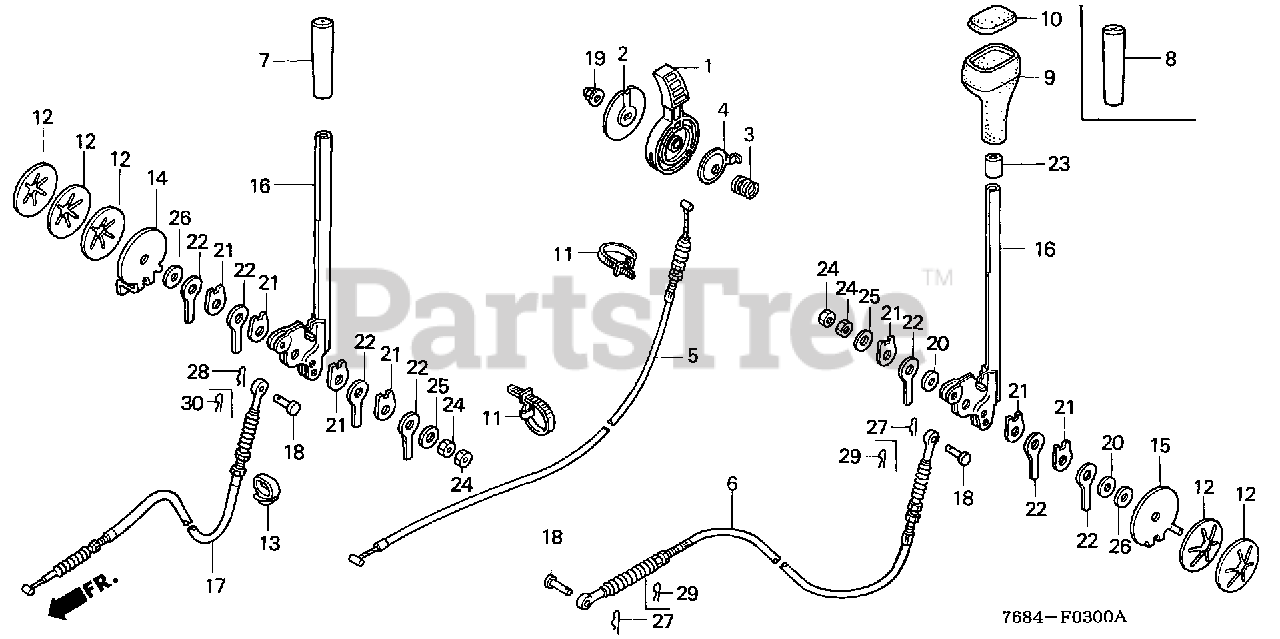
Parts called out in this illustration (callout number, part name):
1	LEVER, THROTTLE
2	PLATE, THROTTLE LEVER
3	SPRING, THROTTLE LEVER
4	SEAT, SPRING
5	CABLE, THROTTLE
6	CABLE, CHANGE
7	GRIP, CHANGE LEVER
8	GRIP, CHANGE LEVER (ORANGE)
12	SPRING, ADJUSTING ARM
13	CLAMP, CABLE
14	PLATE, R. STOPPER
15	PLATE, L. STOPPER
16	LEVER, CHANGE
17	CABLE, CHUTE GUIDE
18	PIN, CONTROL BOX SETTING
19	NUT, CAP (6MM)
20	WASHER, LOCK
21	WASHER, FRICTION
22	WASHER, FRICTION SETTING
23	COLLAR, CHANGE LEVER
24	NUT, HEX. (8MM)
25	WASHER, PLAIN (8MM)
26	WASHER, PLAIN (8MM)
27	PIN, LOCK (6MM)
30	PIN, SPLIT (2.0X12)
